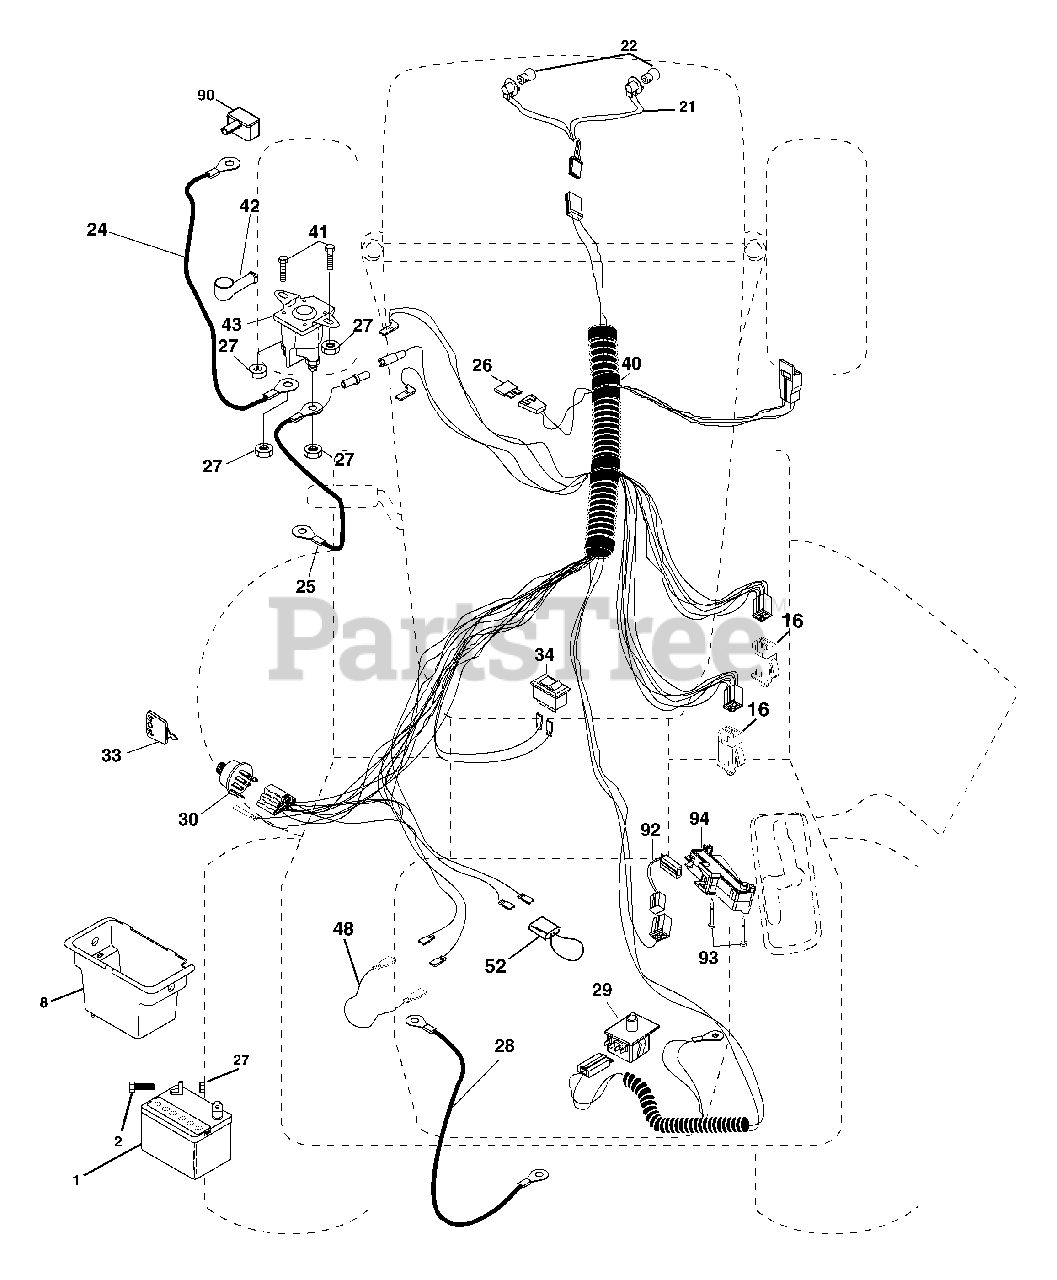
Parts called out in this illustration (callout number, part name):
1	Battery
2	Bolt Hex Hd 1/4-20 unc x 3/4
8	Box Battery
16	Switch Interlock
21	Harness Socket Light
22	Bulb, Light # 1156
24	Cable Battery
25	Cable Battery 6 Ga. Red w/16 wire 44"
26	Fuse
27	Nut Keps Hex 1/4-20 unc
28	Cable Ground 12" Blk 6 Ga.
29	Switch Seat
30	Switch Ign
33	Key Ign Molded Generic
34	Switch Light/Reset
40	Harness Ign
41	Bolt Fin Hex 1/4-20 unc x 1/2
42	Cover Terminal Red
43	Solenoid
48	Adapter Ammeter
52	Protection Loop
90	Cover Terminal
92	Harness Pigtail Reverse Switch
93	Screw Plastite 10-14 x 2.0
94	Module Reverse ROS
